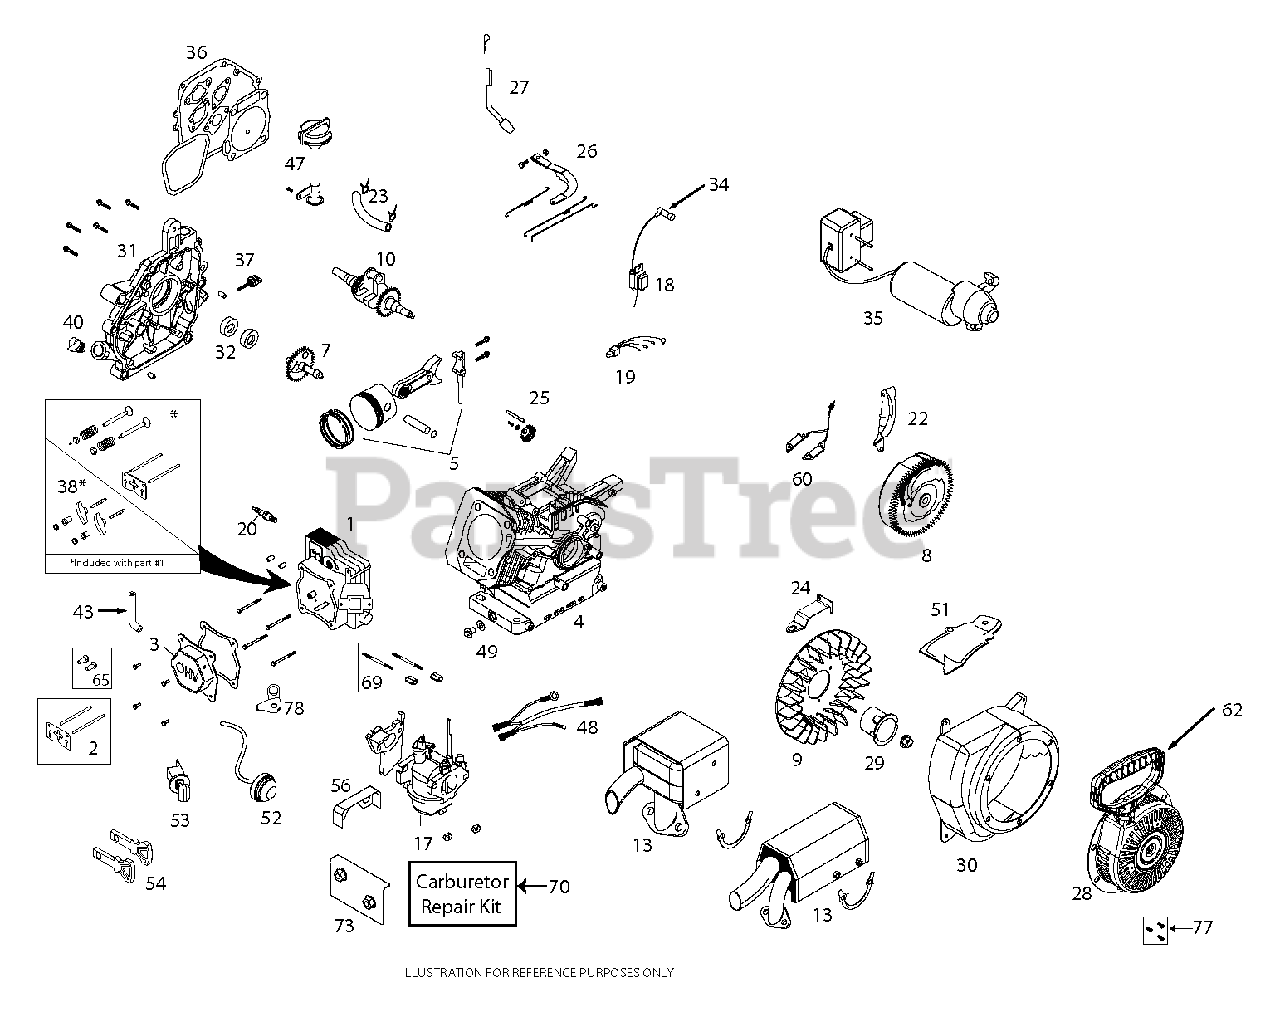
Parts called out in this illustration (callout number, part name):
1	HEAD.CYLINDER.ASSEM.LCT.136CC
2	KIT.PUSH.ROD.LCT.136CC
3	COVER.VALVE.ASSEM.LCT.136CC
4	CYLINDER.ASSEM.LCT.136CC
5	PISTON.&.ROD.ASSEM.LCT.136CC
7	CAMSHAFT.LCT.136CC.
8	FLYWHEEL.MAN.START.136CC.LCT
9	FAN.FLYWHEEL.LCT.SING/STAGE.SN
10	CRANKSHAFT.LCT.136CC
13	MUFFLER.LCT.SINGLE/STAGE.SNOW.
17	CARBURETOR.SNOW.LCT.136CC
18	Ignition Coil, LCT
20	SPARK.PLUG(2083810)
23	KIT.FUEL.HOSE.208CC.SING/STAGE
24	SPEED.CTRL.BRKT.(SKSN0150)
25	GOVENOR.GEARS ASM(SK2082900)
26	ARM.ASM.GOVNR.LCT.136CC
27	SHAFT.GOVERNOR.LCT.136CC
28	RECOIL.STRT.ROUND(BLK) SNOW
29	CUP.STARTER.LCT.136CC.SNOW
30	HOUSING.BLOWER.MANUAL.136CC
31	CRANKCASE COVER.LCT.SKSN1360.1
31	COVER.CRANKCASE.LCT.136CC
32	KIT.ENGINE.SEAL.LCT.136CC
34	SPARK.PLUG.BOOT.SNW,SKSN4691.1
36	KIT.GASKET.LCT.136CC
37	DIPSTICK SMALL
38	KIT ROCKER.ARM.LCT
40	NON REMOVABLE PLUG
43	TUBE.BREATHER.LCT.208
47	HIGH OIL-FILL TUBE ASSY
47	High Oil Fill Tube Assembly
48	WIRING HARNESS LCT.SKSN0162.1
49	KIT.OIL.DRAIN.PLUG(SK2089911
51	CYLINDER COVER
52	BULB.FUEL.PRMR.W/HOSE(SKSNO306
53	SWITH.KEY.ASSEM.SNOW.SINGLE.ST
54	KEY SET(2 KEYS) SKSN0407.1
56	SHIELD.VAPOR.SNOW
62	STARTER.GRIP.SNOW.LCT.SKSN0603
69	CARB.STUDS & COUPLING KIT.SNOW
70	CARB.REPAIR.KIT.LCT.SK9900.1
73	SHIELD.INTAKE.(LCT.SKSN0140.1)
77	BOLT.KIT.RECOIL.LCT.ALL.ENGINE
